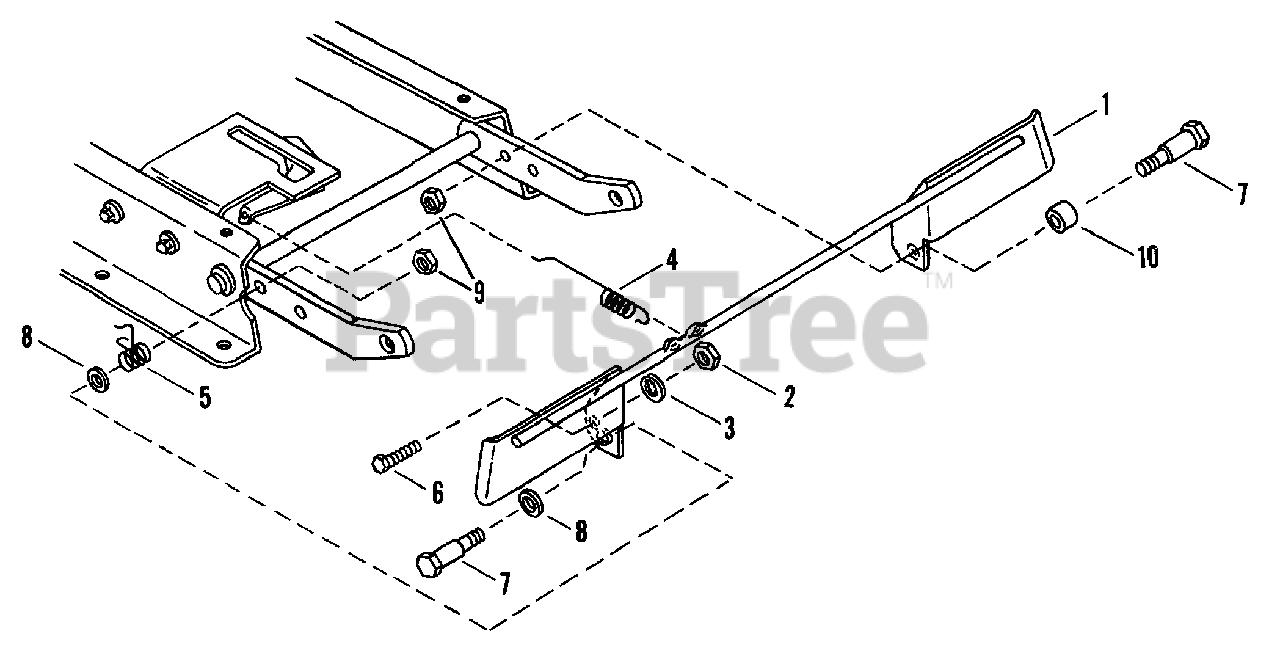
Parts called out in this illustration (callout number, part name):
1	PEDAL, Blade Stop Control
2	NUT, 1/4-28 Hex
3	WASHER, 1/4 Internal Tooth Lock
4	SPRING, Latching
5	SPRING, Pedal
6	SCREW,1/4-28x1" Hex Head Cap
7	BOLT, 3/8-24x1 3/4" Shoulder
8	WASHER, 1/2 Flat
9	NUT, 3/8-24 Hex
